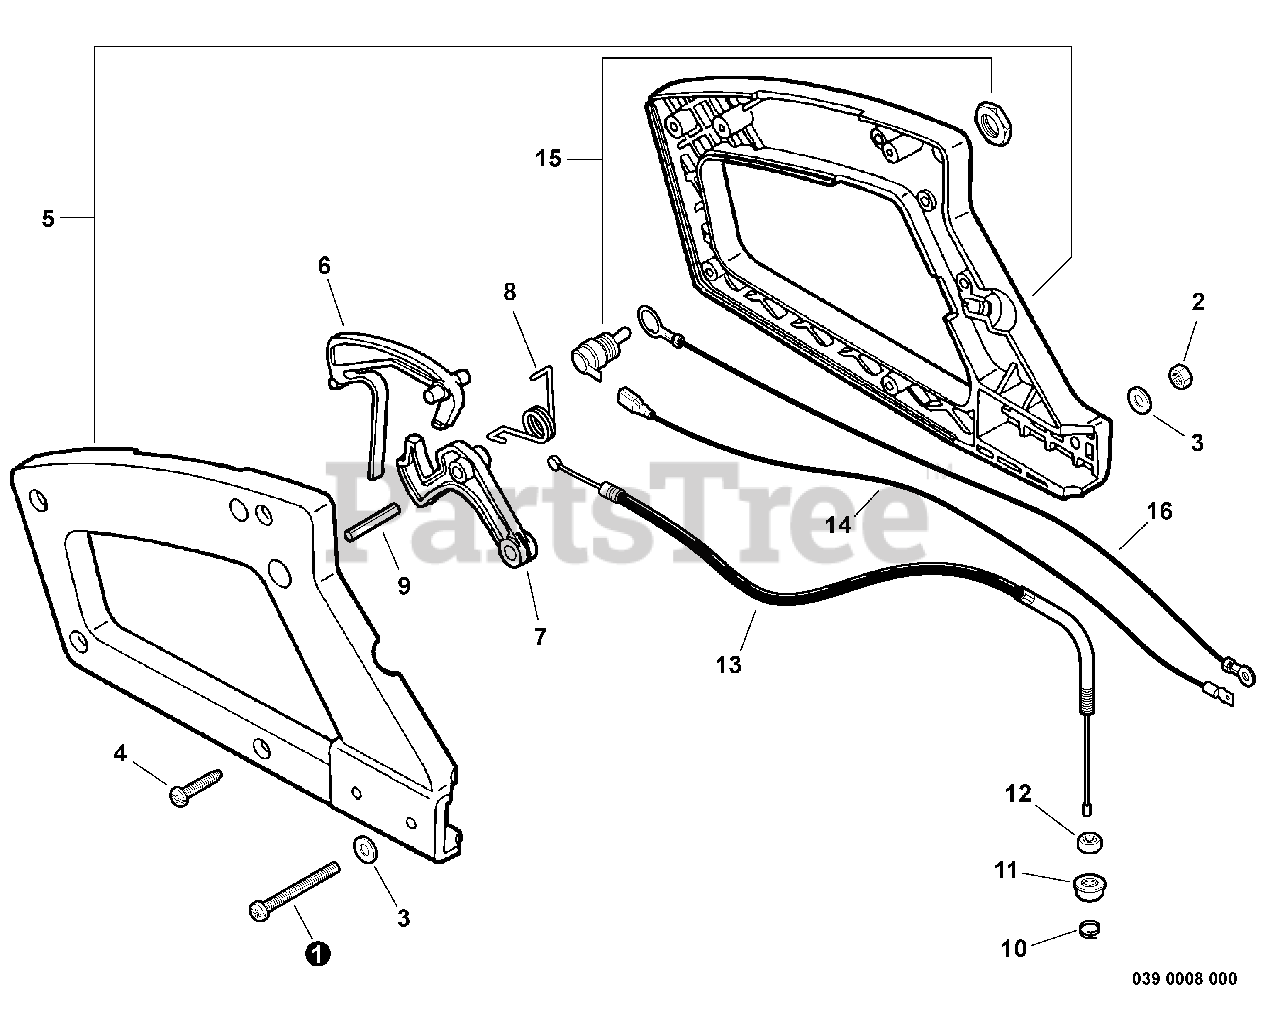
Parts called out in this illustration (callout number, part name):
1	SCREW 5×47
2	NUT, LOCK M5
3	WASHER, FLAT 5.5×10×0.8
4	SCREW 4×16
5	HANDLE SET, REAR
6	LOCKOUT, THROTTLE
7	TRIGGER, THROTTLE
8	SPRING, THROTTLE RETURN
9	PIN, SPRING Ø5×25 MM
11	NUT, FLANGE M6×1
13	CABLE, THROTTLE
14	LEAD - IGNITION
15	SWITCH, ON-OFF
16	LEAD - GROUND
